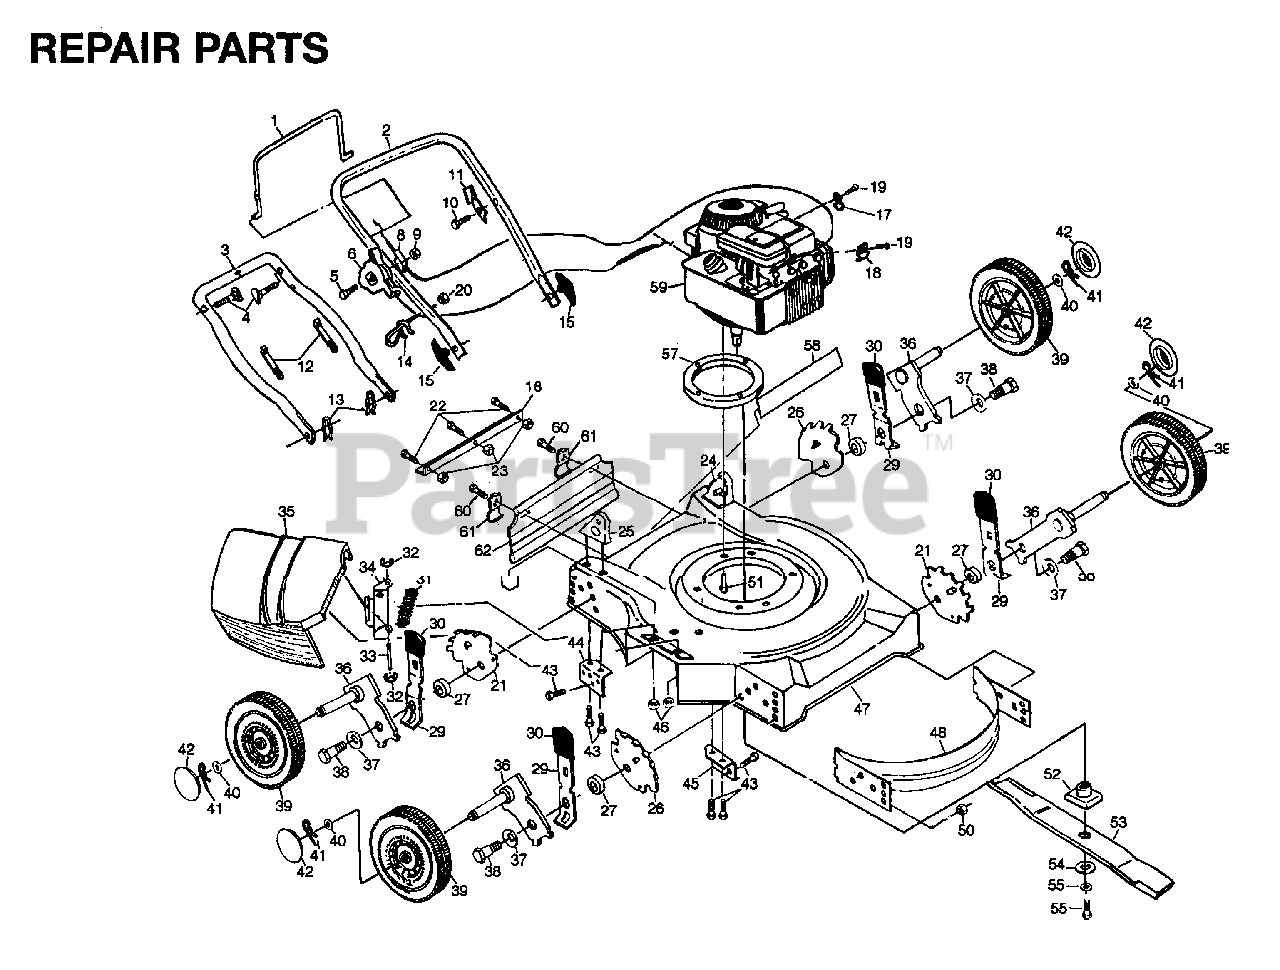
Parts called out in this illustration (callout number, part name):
1	CONTROL BAR
3	LOWER HANDLE
4	HANDLE BOLT
5	SCREW 1/4-20 X 2.12
6	THROTTLE CONTROL
8	ENGINE ZONE CONTROL CABLE
9	NUT.CROWNLOCK.1/4
11	BRACKET UPSTOP
12	TIE GUIDE
13	HAIRPIN COTTER
14	ROPE GUIDE
15	HANDLE KNOB
17	GUIDE CLIP PM
18	WASHER
19	SCREW.HEX.HEAD.WASHER.10-16
20	NUT.CROWNLOCK.1/4
21	BRACKET.WHL.ADJ.L
23	NUT.CROWNLOCK.1/4
24	HANDLE BRKT ASSY LH
25	HANDLE BRKT ASSY RH
26	BRACKET.WHL.ADJ.R
27	SPACER PM
29	SELECTOR SPRING
31	SPRING PM
34	BRACKET PM
36	AXLE ARM
37	BELLEVILLE WASHER
38	SHOULDER BOLT PM
40	WASHER
41	RETAINER CLIP PM
43	SCREW
46	NUT.CROWNLOCK.1/4
50	LOCKNUT
52	BLADE ADAPTOR
53	%20"BLADE (FOR MODELS 50/51)
54	WASHER,HARDEN
55	LOCKWASHER
56	SCREW, HEX HD 3/8-24 X 1-3/8
61	BRACKET DEFL PM
62	REAR SKIRT
63	CLIP,CABLE
